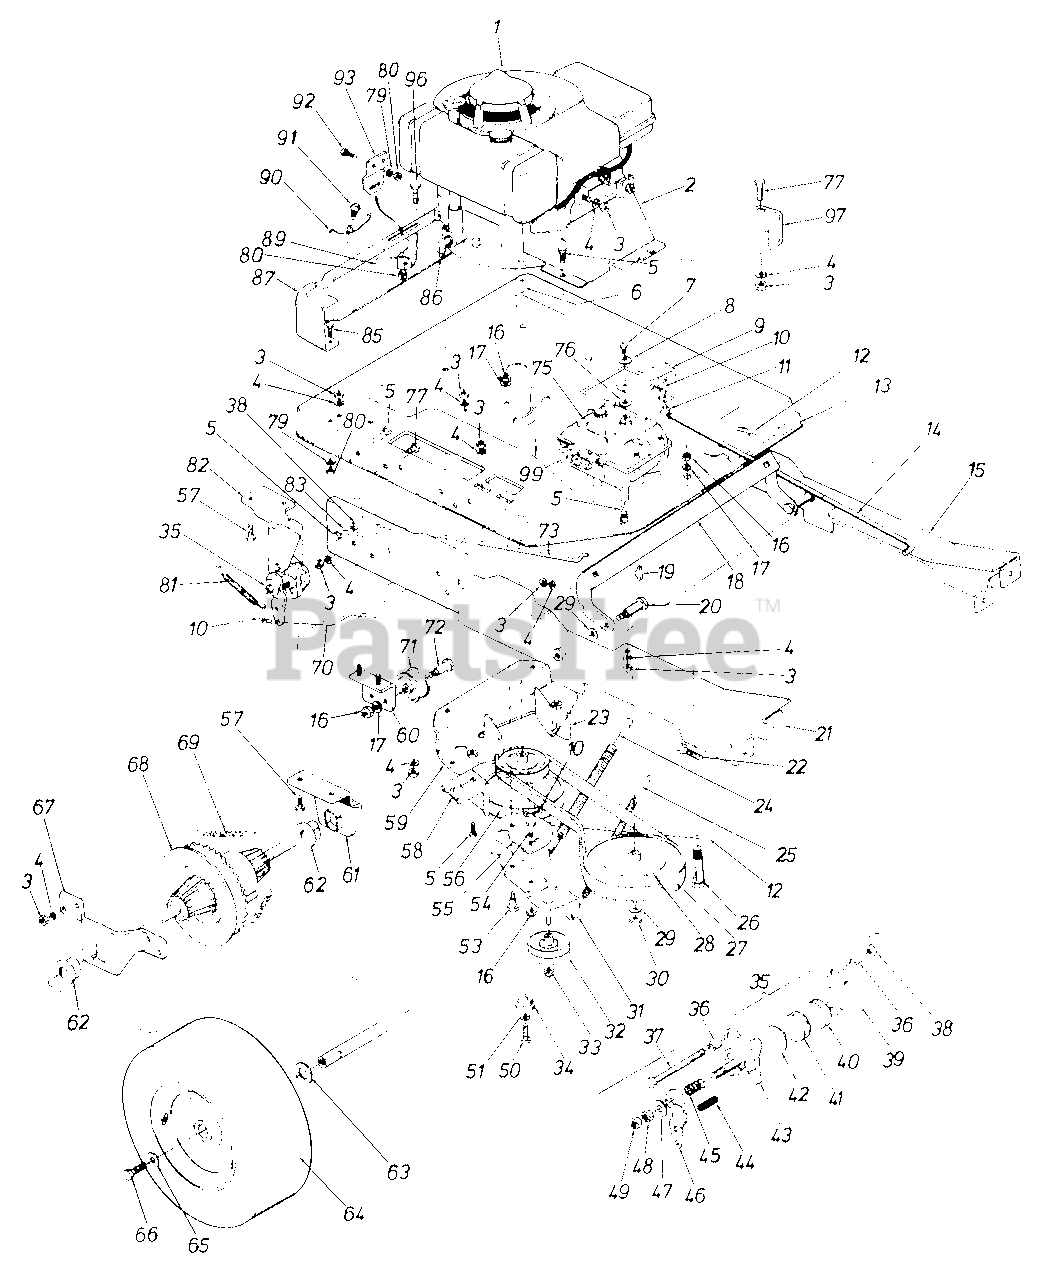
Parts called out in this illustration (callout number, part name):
1	Engine
2	Hot Air Duct
3	Hex Nut 5/16-18 Thd.
4	L-Wash. 5/16 Scr.
5	Hex Sems Scr. 5/16-18 x .75
6	#6 Hi-Pro Key 5/32 x 5/8 Dia.
7	Hex Scr. 5/16-24 x .50 Lg.
8	Belleville Wash. .345 I.D.
9	Shift Brkt.
10	Cotterpin 3/32 x .75
11	Adjustment Ferrule
12	Clutch Rod
13	Engine Mtg. Plate
14	Shift Rod
15	Slide Rail L.H.
16	Hex Cent. L-Nut 3/8-16 Thd.
17	Spring L-Wash. 3/8 Scr.
19	#4 Hi-Pro Key 3/32 x 5/8" Dia.
20	Shld. Scr. .625 Dia. x 1.5" Lg.
21	Side Rail Ass'y. R.H.
22	Hex Scr. 3/8-16 x .75 Lg.
23	Belt Keeper
24	Ext. Spring
25	Tension Spring
26	Shld. Scr. .62 x 1.75
27	V-Belt 1/2 x 48
28	Transmission Pulley
29	Spring L-Wash. 1/2 Scr.
30	Hex Jam Nut 1/2-20
31	Idler Brkt. Ass'y.
32	Flat Idler
33	Hex Ins. L-Nut 3/8-24"
34	Step Washer
35	Brake Ass'y. - Comp.
36	Bushing .442 Dia. x .375 Lg.
37	Hex Scr. 5/16-18 x 2.25 Lg.
38	Hex Cent. L-Nut 5/16-18 Thd.
39	Casting Carrier
40	Friction Pad 1.110 Dia. x .245 Thick
41	Friction Pad 1.110 Dia. x .430 Thick
42	Back Up Washer
43	Casting Cam
47	Washer
48	Hex Top L-Nut
49	Hex Centerlock Nut
50	Hex Scr. 3/8-24 x 1.75 Lg. H.T.
51	Spring L-Wash. 3/8 Scr.
53	Shld. Scr. .500 Dia. x .340
54	Shld. Scr. .500 Dia. x .170
55	Idle Pivot Brkt.
56	Two Step Engine Pulley
58	Belt Keeper
59	Belt Guard Ass'y.
60	Chain Idler Ass'y.
61	Bearing Support
62	Flange Bearing - Plastic
63	Flat Washer .812 I.D.
64	Rear Wheel Ass'y. - Comp.
65	Belleville Washer
66	Hex Scr. w/Lock 5/16-24 x .75 Lg.
67	Bearing Brkt.
68	Differential Ass'y. - Comp.
69	#420 Chain 1/2 x 71 Links
70	Brake Rod
71	Flat Idler
72	Shld. Scr. .500 x .48 Lg.
73	Rear Cover Prop
75	Transmission 4 Speed - Peerless
76	Hardened Washer
77	Hex Sems Scr. 5/16-18 x 1 Lg.
79	L-Wash. 1/4 Scr.
80	Hex Nut 1/4-20 Thd.
81	Brake Return Spring
82	Brake Hanger Brkt.
83	Flat Wash. .344 I.D.
85	Hex Scr. 1/4-20 x .50 Thd.
86	90° Elbow Male to Female 3/8" Thd.
87	Rear Panel
89	Hook Brkt.
91	Shld. Scr.
92	Carr. Bolt 1/4-20 Thd.
93	Latch Brkt.
96	Hex Scr. 5/16-18 x 1 1/2 Lg.
97	Belt Guide
